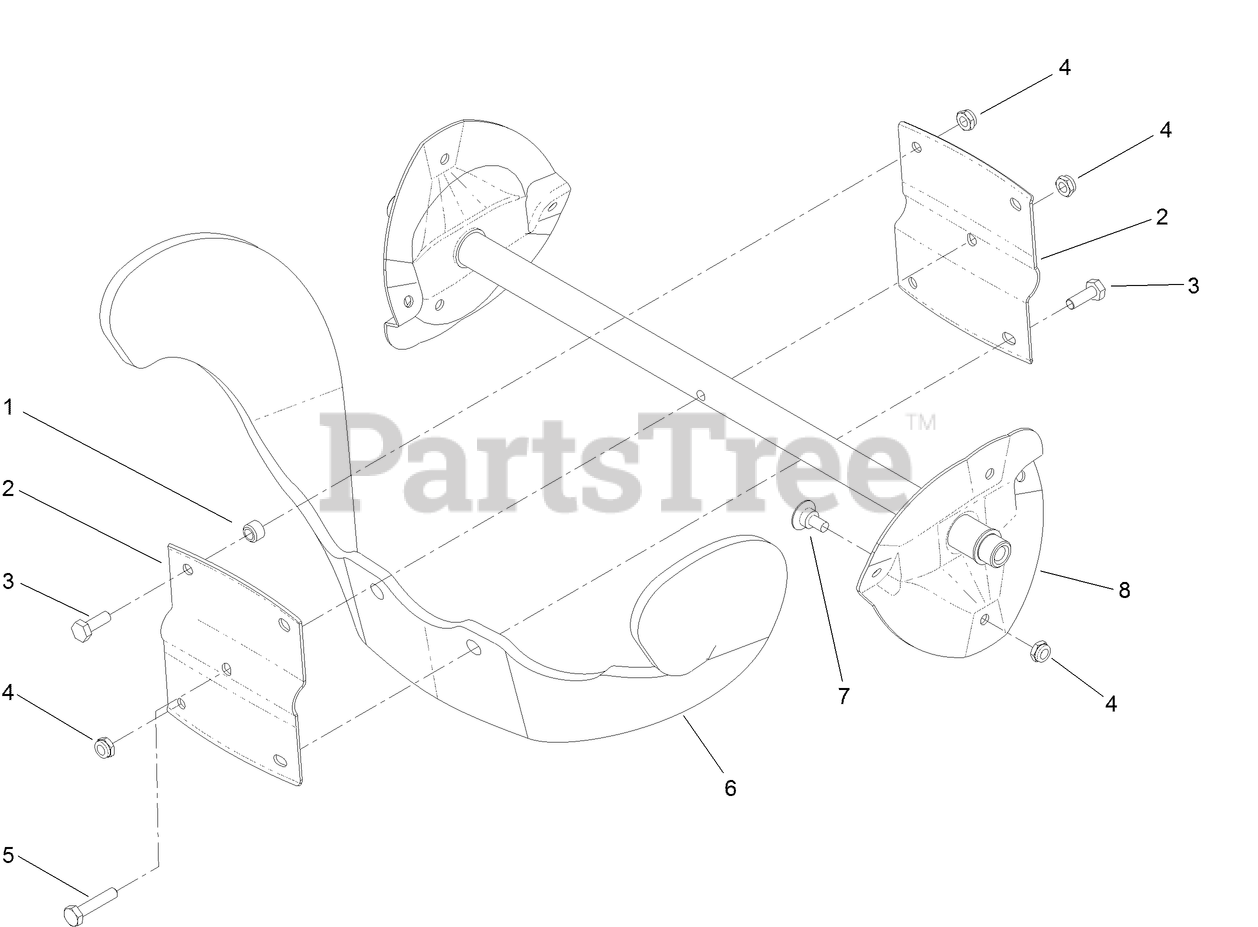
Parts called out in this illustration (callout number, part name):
1	SPACER-BLADE, ROTOR
2	HALF-ROTOR
3	SCREW-HH
4	NUT-LOCK, NI
5	SCREW-HH
6	BLADE-ROTOR
8	ROTOR KIT
